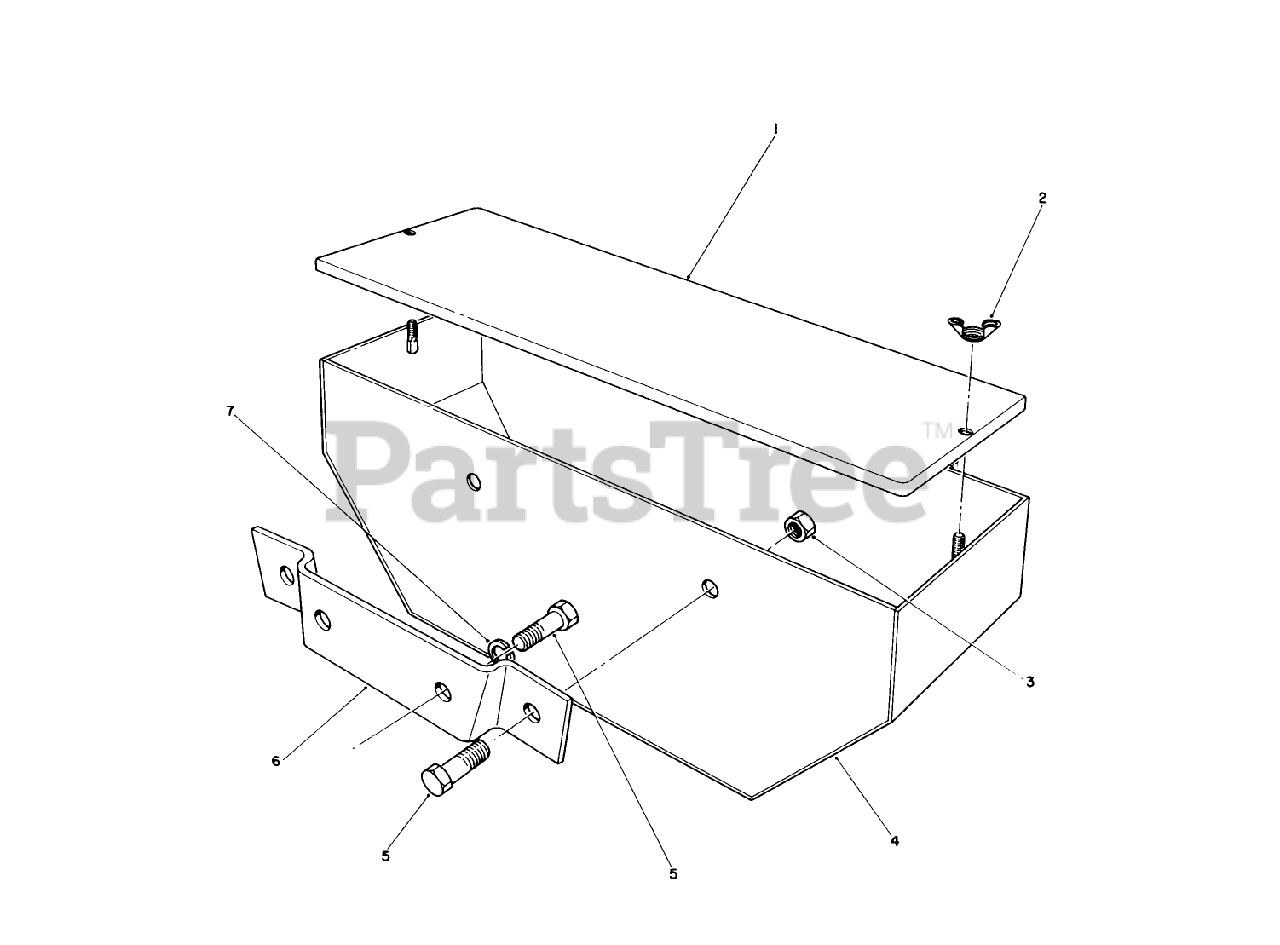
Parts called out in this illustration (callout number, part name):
1	WT BOX COVER R
2	NUT-WING
3	NUT-LOCK, NI
4	WEIGHT BOX WA
5	SCREW-HH
6	MOUNT BRKT R
7	WASHER-LOCK
